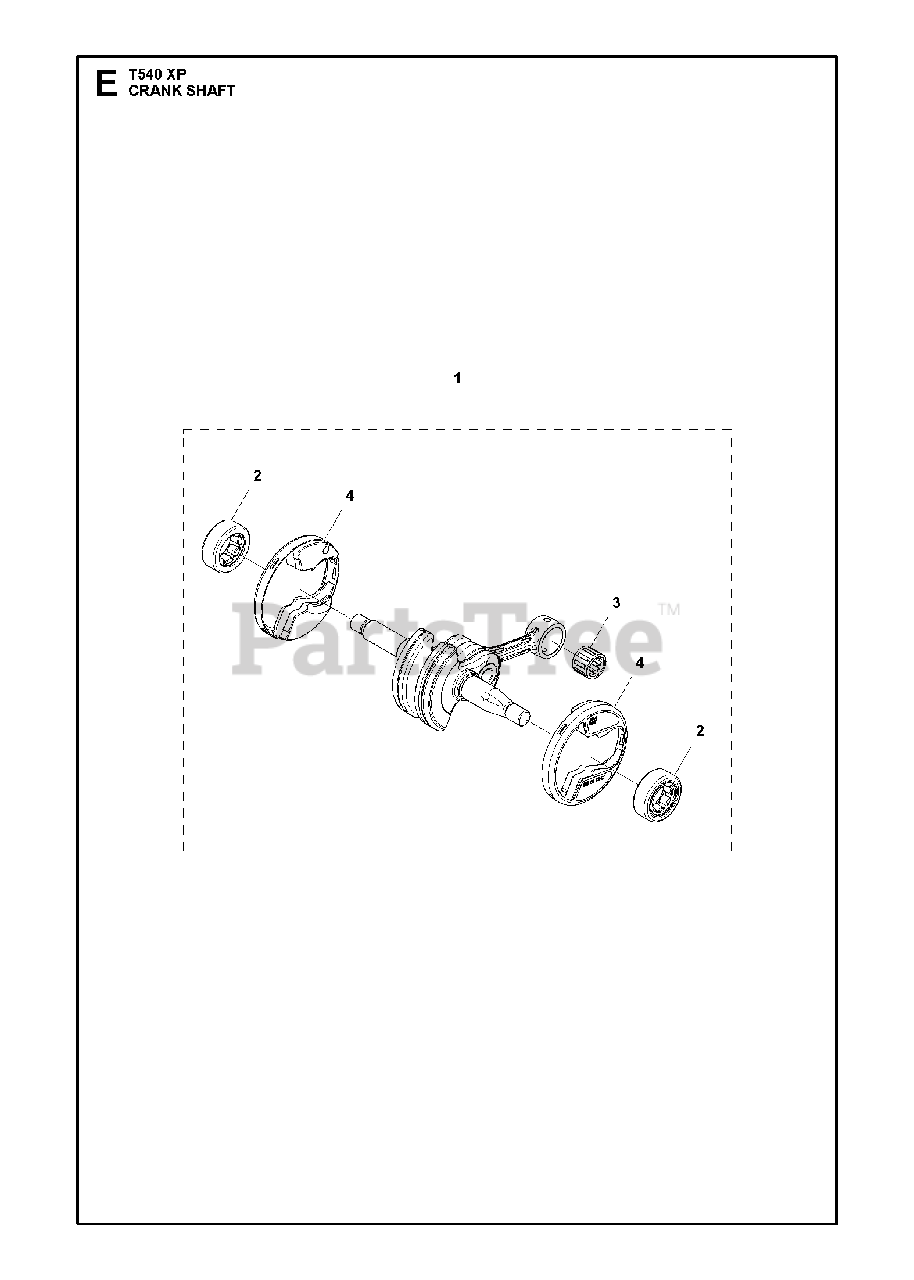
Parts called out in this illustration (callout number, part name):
1	CRANKSHAFT ASSY
2	ROLLER BEARING
3	NEEDLE BEARING
4	CUP
